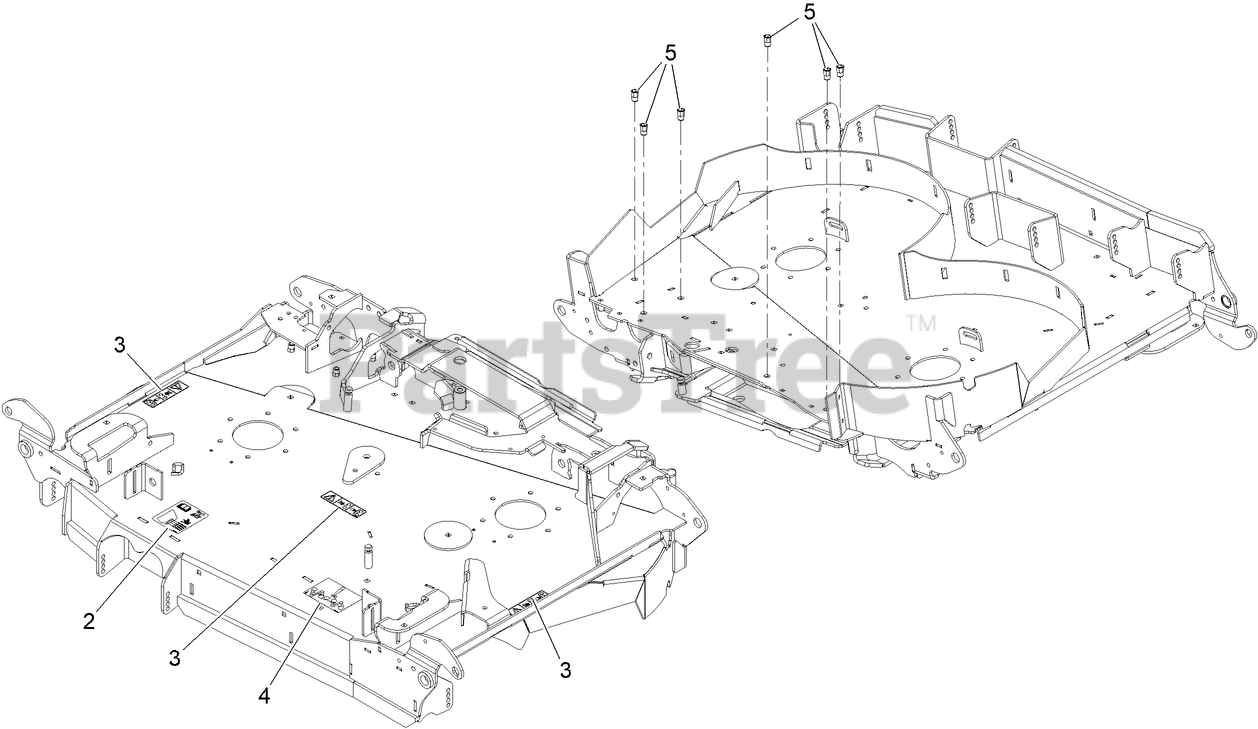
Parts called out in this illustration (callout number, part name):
2	DECAL-ROLLER, ANTI-SCALP
3	DECAL-COVER, MISSING
4	Decal-Belt Routing
5	NUT-CLINCH,HEX
